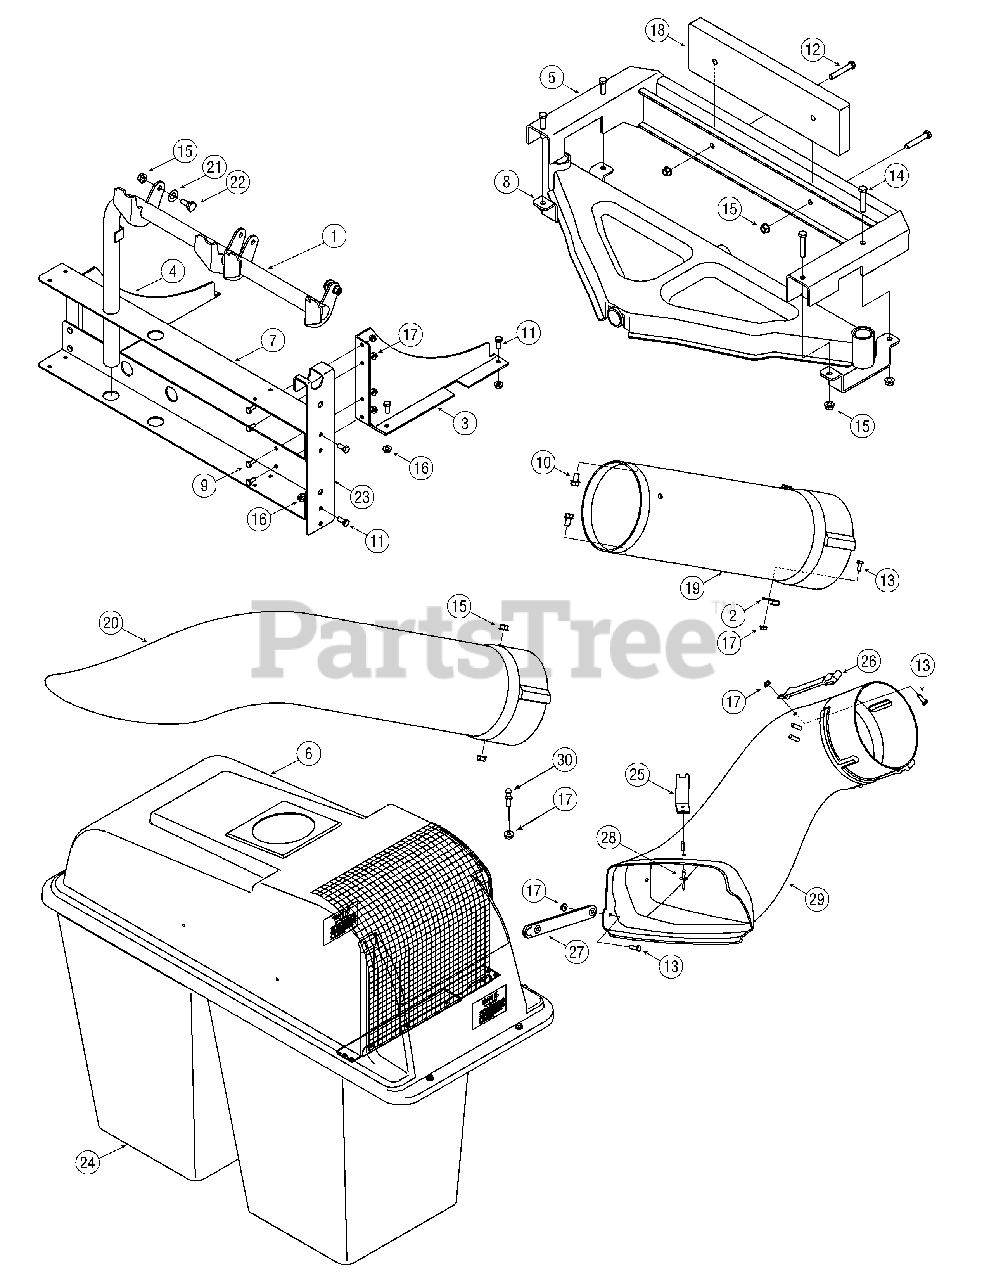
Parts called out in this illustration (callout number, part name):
2	Retainer Hook
6	Grasscatcher Cover Assembly
9	Hex Bolt 1/4-20 x .620
10	Hex Washer Hd. Bolt 3/8-16 x .625
11	Hex Bolt 5/16-18 x .75
12	Hex Bolt 3/8-16 x 2.25
13	Hex Bolt 1/4-20 x .75
14	Hex Bolt 3/8-16 x 2.0
15	Top Lock Flange Nut 3/8-16
16	Flange Lock Nut 5/16-18
17	Flange Lock Nut 1/4-20
18	Weight Bar
19	Chute Extension
22	Shoulder Screw
24	Grass Bag Assembly
24	Screw, #10-24 x .5
24	Hex Sems Nut, 10-24
24	Bag
24	Self Tapping Screw, 5/16-18 x .625
26	Retainer Strap
28	Rivet .187 Dia. #66
29	Chute Elbow
30	Grasscatcher Pin
